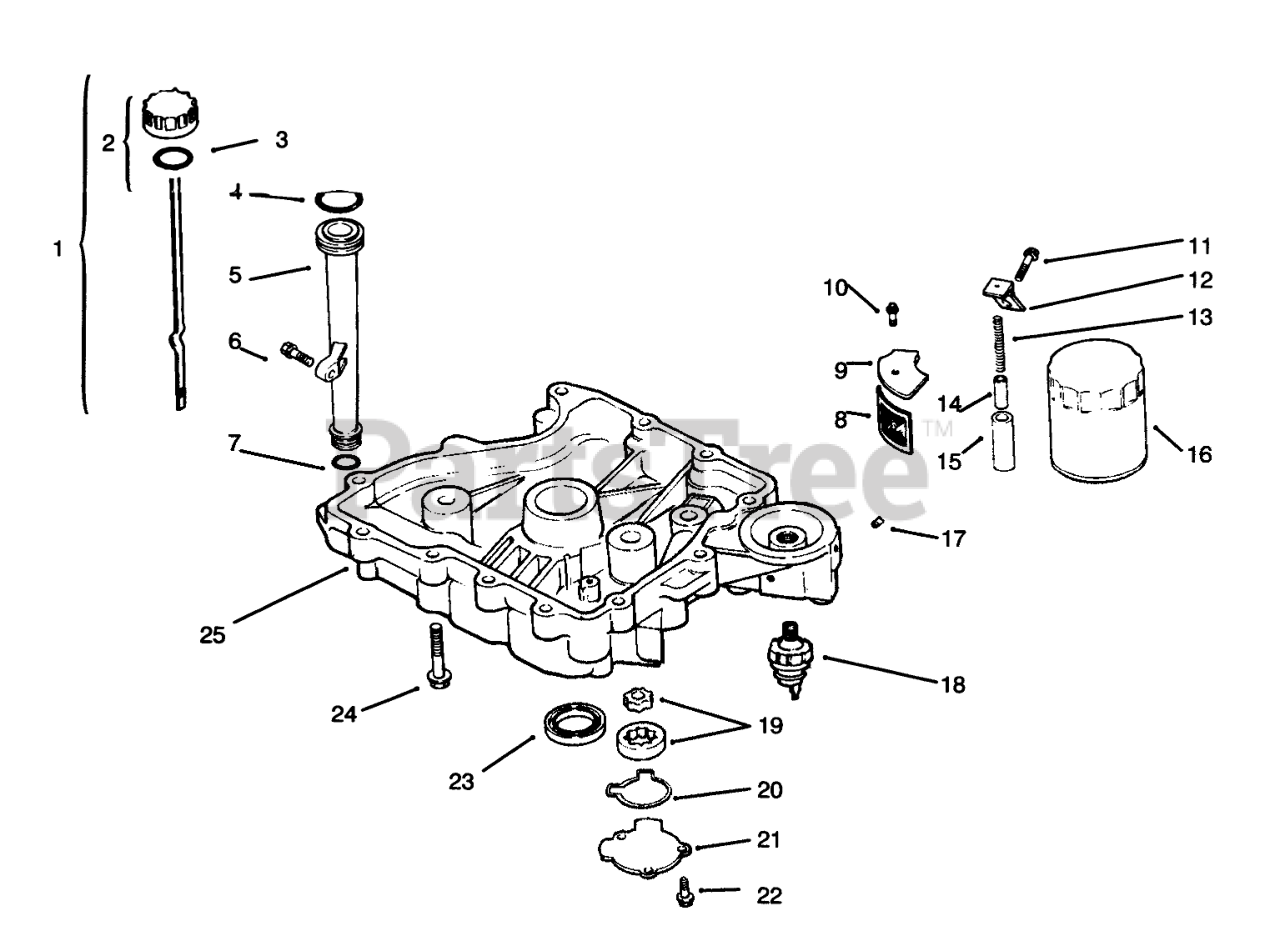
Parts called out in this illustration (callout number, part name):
1	Dipstick INC 2-3
2	Kit-Oil Cap INC 3
3	"O"Ring
4	"O"Ring-Upper Tube
5	Tube-Oil Fill
6	Screw
7	"O"Ring
8	Screen-Oil Pickup
9	Cover-Oil Screen
10	Screw-HF
11	Screw
12	Bracket-Relief Valve
13	Spring-Relief Valve
14	Piston-Relief Valve
15	Body-Relief Valve
16	Filter-Oil
17	Plug
18	Switch-Oil Pressure
19	Pump-Oil
20	"O" Ring-Oil Pump
21	Cover-Oil Pump
22	Screw-HF
23	Seal-Oil
24	Screw M8x1.25x45
25	Pan-Oil
